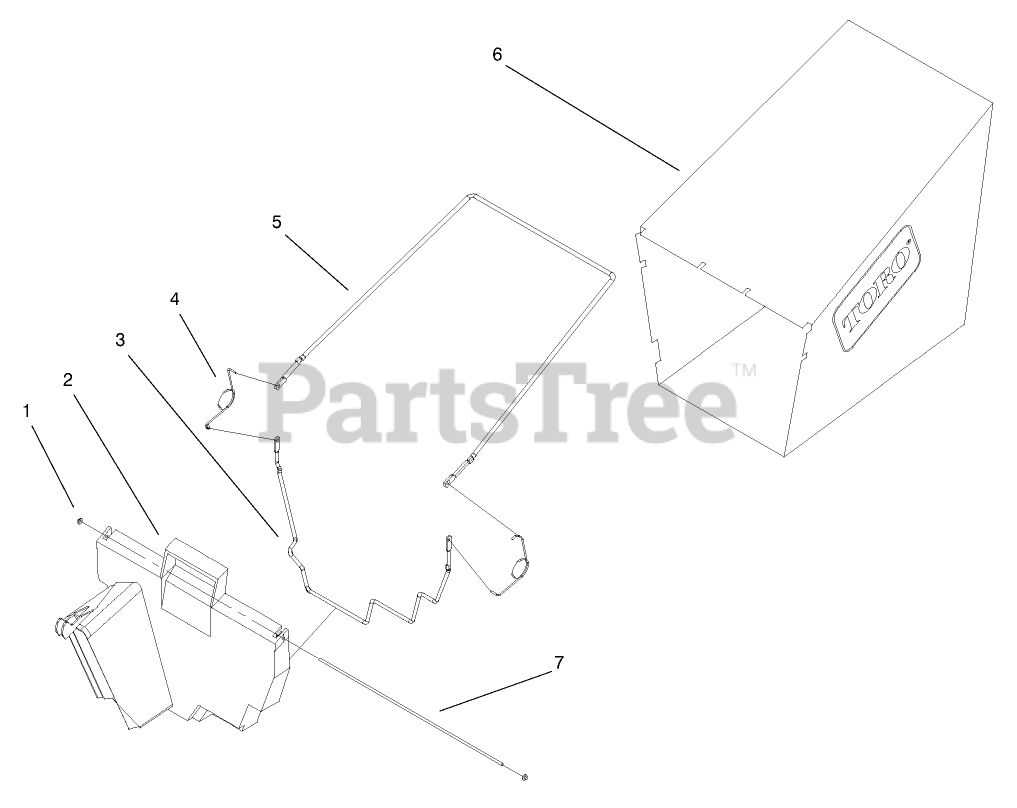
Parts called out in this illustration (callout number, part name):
1	NUT-PUSH
2	DOOR-BAG
3	FRAME-BAG, LOWER
4	SPRING
5	FRAME-BAG, UPPER
6	BAG-GRASS
7	HINGE-DOOR, BAG
